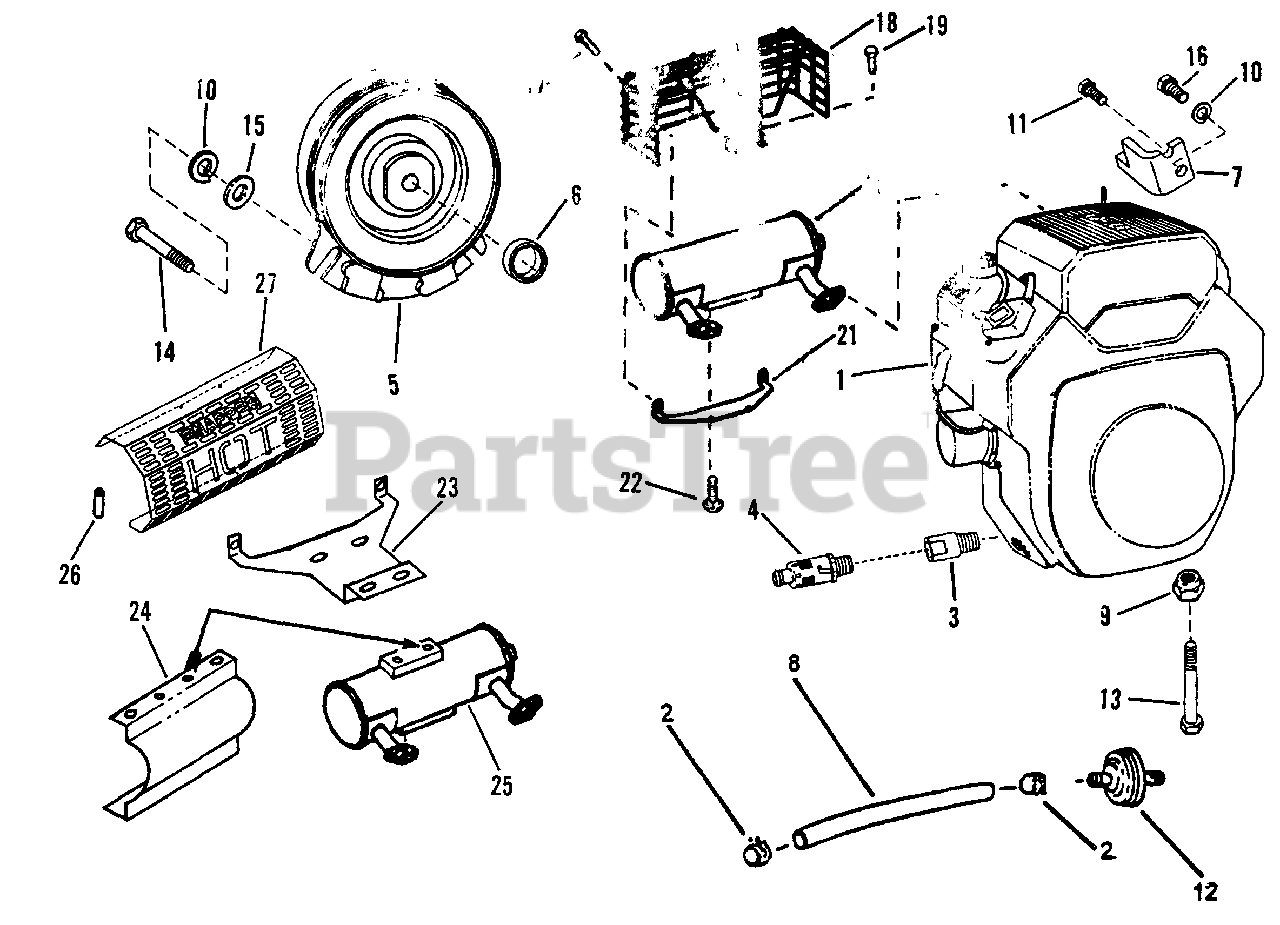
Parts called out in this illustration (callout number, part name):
1	ENGINE, 22 HP
2	CLAMP, Fuel Hose
3	OIL DRAIN, Short
4	ASSEMBLY, Oil Valve
5	CLUTCH, Electric, Commercial Magstop
6	SPACER, Clutch
7	BRACKET, Anti-Rotation (5/16")
8	HOSE, Fuel 1/4 x 4"
9	NUT, 3/8-16 HEX NYLON LOCK
10	WASHER, 7/16" Split Lock
11	BOLT, 3/8-16 X 1" GD5 CZ
12	FILTER, Fuel (in-line)
13	SCREW, 3/8-16 x 1-3/4" Hex Head Cap, Grade 5
14	SCREW, 7/16-20 x 1-1/2" Hex Head Cap Grade 5
15	WASHER, 15/32 I.D x 1-3/8 O.D x 1/4 Flat
16	PIN, COTTER, 1/8 X 1-1/4
17	SCREW, M5 x 10mm Pan Head Cap
18	GUARD, Muffler
19	SCREW, M5 x 16mm Hex Head Self Tapping
20	MUFFLER, 22 HP
21	BRACKET, Muffler
22	SCREW, M6 x 12.5mm Hex Flange Cap
23	BRACKET, Muffler 25 HP Kohler
24	SHIELD, Heat 25 HP Kohler
25	MUFFLER, 25 HP
26	SPACER, Muffler Guard
27	GUARD, Muffler "Snapper"
